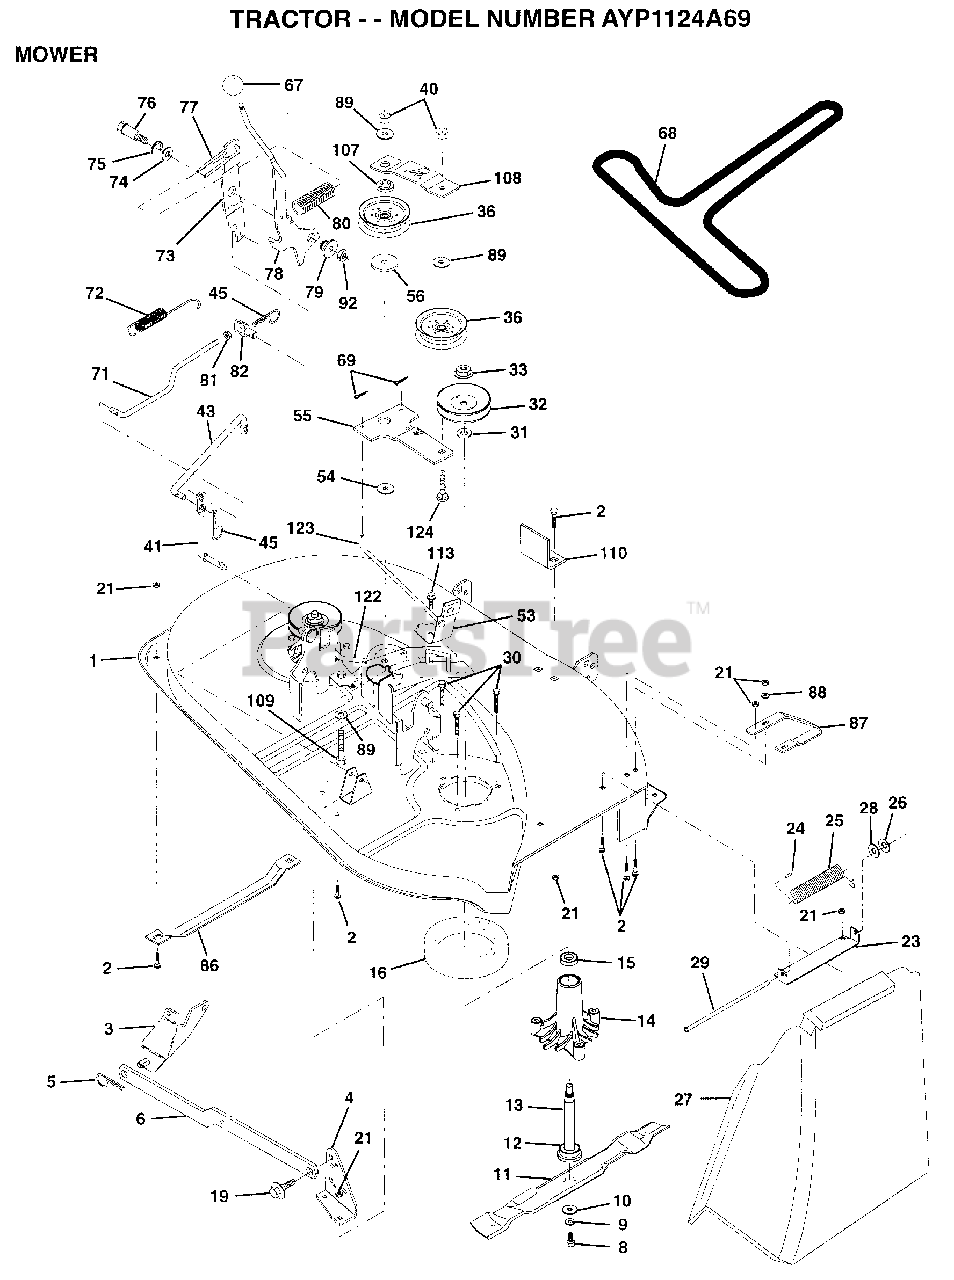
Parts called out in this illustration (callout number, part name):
2	BOLT
3	BRKT ASM SWAY BAR
4	BRKT DECK SW BAR
8	BLADE BOLT
10	WASHER.HARD.BLADE
11	"BLADE.38""V.MULCH"
12	BEARING.BALL
14	HSG ASM MANDREL
15	BEARING
16	STRIPPER RND MWR
19	BOLT SHD 5/16-18
23	BRKT DEFLECTOR
24	CAP-SLEEVE LT
25	SPRING TORSION
26	NUT PUSH M
27	DEFLECTOR-SHLD T
28	WASHER
29	ROD-HINGE T
31	WASHER
36	FLAT IDLER PULLEY
41	PIVOT ROD
43	CLUTCH ROD SECOND
45	RETAINER M
53	BRAKE ASM
54	HARDENED WASHER
55	IDLER ARM ASSY
56	SPACER RETAINER
67	KNOB T (1/2-HOLE)
68	BELT.V.T-PATH
71	ROD CLUTCH 38/42
72	RETURN SPRING
73	CLUTCH ARM SECOND
74	WASHER
75	RING
76	SHOULDER BOLT
77	SPRING KEEPER
79	BUSHING
81	NUT
82	TRUNION ADJ
86	RUNNER-LH M
87	RUNNER RH
88	WASHER M
89	WASHER GT
92	NUT
107	RETAINER SPACER
108	IDLER ARM STIFF
109	BOLT
110	UPSTOP DECK FT 38
113	SCREW
122	BRAKE ROD LH
123	BRAKE ROD RH
124	BOLT
